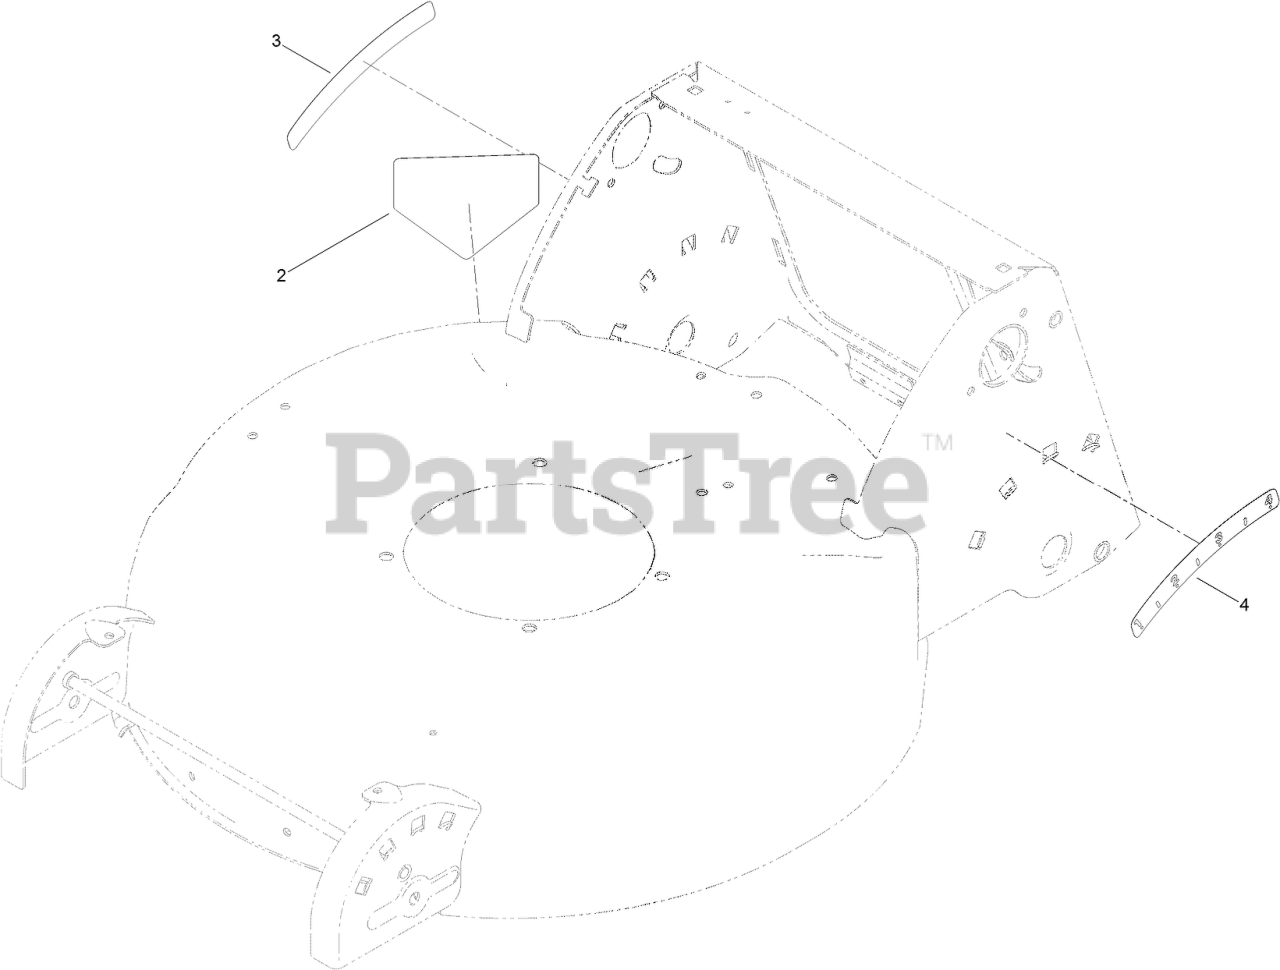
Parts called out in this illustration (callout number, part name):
2	DECAL-DANGER
3	DECAL-HOC, RH
4	DECAL-HOC, LH
